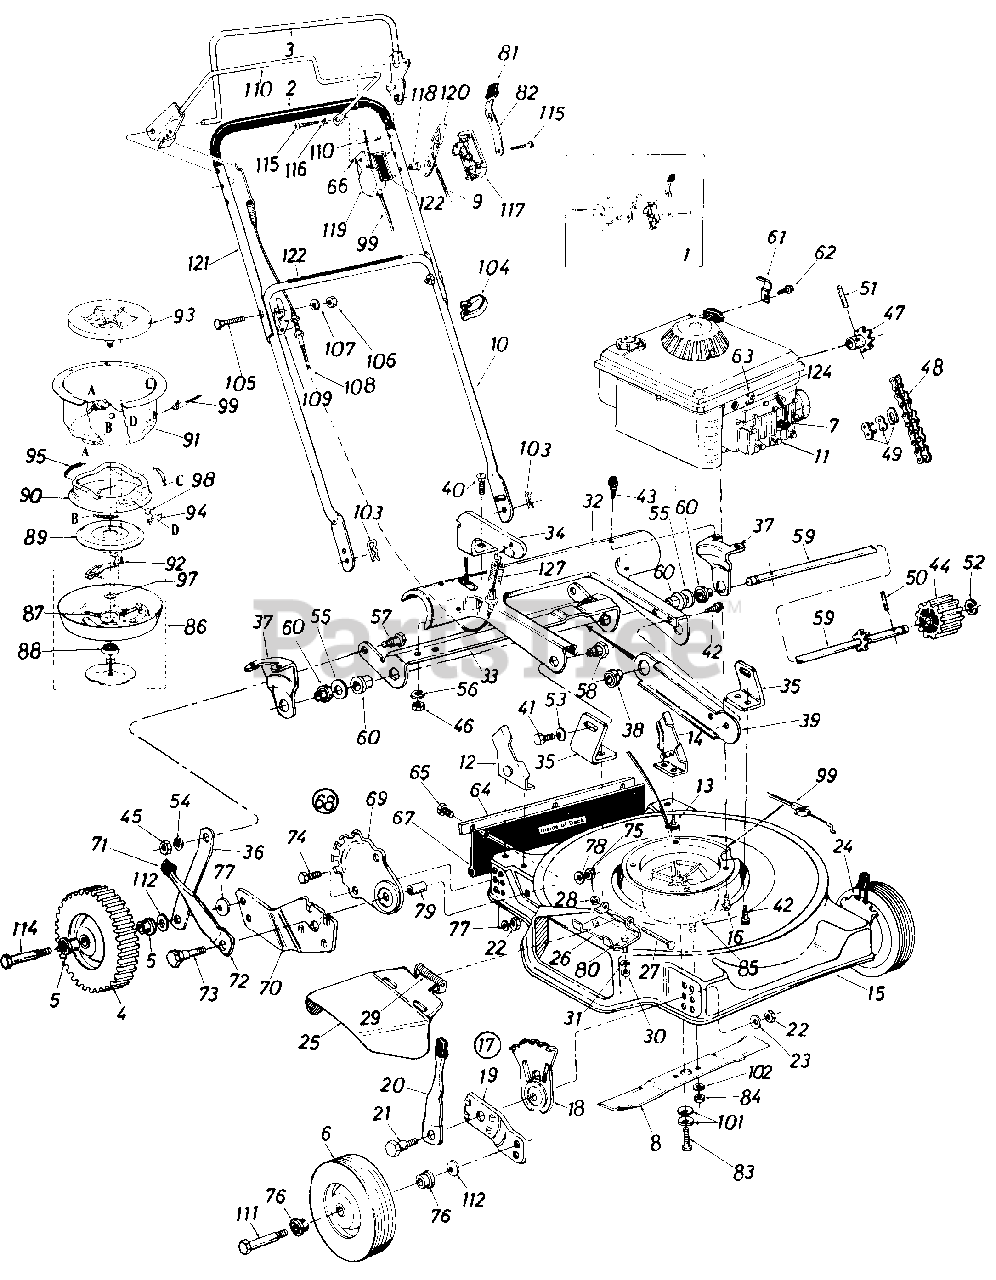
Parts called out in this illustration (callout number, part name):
1	Kit-Control Housing Comp.
3	Control Handle Ass'y. Comp.-L.H .
4	Rear Wheel Ass'y.-Comp. 8 x 1.75
5	Rear Wheel Brg.
7	Spark Plug Boot
8	22" Blade
9	Throttle Control Wire-53"
10	Lower Handle
11	Engine
12	Handle Brkt. Ass'y.-R.H.
13	Hex Wash. Hd. "B"-Tap Scr. 5/16-18 x .50" Lg.
14	Handle Brkt. Ass'y.-L.H.
15	22" Deck Ass'y.
16	Hex Wash. Hd. TT-Tap Scr. 3/8-16 x 1.00" Lg.
17	Height Adj. Ass'y. Comp.- R. H .
18	Height Adj. Plate
19	Pivot Bar
20	Spring Lever w/Knob
21	Shld. Bolt .500" Dia. x .375
22	Hex Nut 3/8-16 Thd.*
23	Bell-Wash. .39" I.D. x 1.4"
24	Height Adj. Ass y. Comp.-L.H.
25	Chute Deflector Ass'y. Comp.
26	Deflector Hinge Plate Ass'y.
27	Pivot Pin
28	Push Cap 1/4" Rod
29	Torsion Spring
30	Hex Nut 1/4-20 Thd.
31	L-Wash. 1/4" I.D.
32	Pinion Pivot Cover 22"
33	Cam
34	Engagement Arm
35	Pivot Bracket
36	Link 4.58" x .88" Wide
37	Axle Brkt.
38	Flange Ball Brg. .500" I.D.
39	Brg. Support
40	Carriage Bolt 1/4-20 x .50" Lg.
41	Hex Bolt 3/8-16 x .50" Lg.
42	Hex "B"-Tap Scr. 1/4 x .38"
43	Hex Wash. Hd. AB-Tap Scr. 1/4" x.62" Lg.
44	13 Teeth-Drive Pinion
45	Hex Nut 5/16-18 Thd.
46	Hex Nut 1/4-20 Thd.
47	10 Tooth Sprocket Ass'y.
48	#48 Chain 1/2" Pitch 49 Links
49	Master Link
50	Spring Pin Spir. 3/16" Dia. x 1.25" Lg.
51	Spring Pin Spir. 3/16" Dia. x 1.00" Lg.
52	"E"-Ring For. 500" Dia. Shaft
53	Bell-Wash. .400" I.D. x .88"
54	L-Wash. 5/16" I.D.
55	Fl-Wash. .531" I.D. x .930"
56	L-Wash. 1/4" I.D.
57	Shoulder Bolt .437" I.D. x .1 62
58	Shoulder Nut .625" Dia. x .1 65
59	Pinion Shaft wl7 Tooth Sprocket
60	Flange Brg. .506" I.D.
61	Casing Clamp
62	Hex "B" Tap Scr. #10 x .38" Lg.
63	Casing Clamp
64	Retaining Strip
65	Hex AB-Tap Scr. 1/4 x .62" Lg.
66	Fl-Wash. .203 I.D. x .406 O.D.
67	Rear Flap Ass'y.
68	Rear Height Adj. Ass'y. Comp.-R.H.
69	Index Plate
70	Pivot Bar-R.H.
71	Spring Lever Knob
72	Spring Lever
73	Shoulder Bolt .500" Dia. x .433" Lg.
74	Hex Bolt 3/8-16 x .75" Lg.
75	Hex Cent. L-Nut 5/16-18 Thd.
76	Front Wheel Bearing
77	Bell-Wash. .400" I.D. x .88"
78	Bell-Wash. .345" I.D. x .88"
79	Spacer.383" I.D. x .503" O.D. x .562" Lg.
80	Hex Bolt 1/4-20 x .50" Lg.
81	Spring Lever Knob
82	Lockout Lever
83	Hex Bolt 3/8-24 x 2.00" Lg. (Grade 8)
84	Hex Nut 3/8-24 Thd. (Grade 8)
85	Blade Brake Clutch Comp.
86	Clutch Blade Housing Ass'y.
87	Compression Spring .35" O.D. x 2.00" Lg.
88	Ball Brg. .669" I.D. x 1.574n
89	Clutching Cone
90	Brake Cup Cone
91	Clutch Housing
92	Hex Tap L-Scr. 1/4-20 x .75"
93	Fan Adapter
94	Ball Block
95	Extension Spring .35" O.D. x 1.75" Lg.
97	Fl-Wash. .690" I.D. x 1.060" O.D.
98	Steel Ball.500" Dia.
99	Clutch Cable-42.0"
101	Bell-Wash. .400" I.D. x .88"
102	L-Wash. 3/8" I.D.*
103	Intern. Cot. Pin 5/16" Dia.
104	Cable Tie
105	Curved Carriage Bolt 5/16-18 x 1.38" Lg.
106	Hex Nut 5/16-18 Thd.*
107	L-Wash. 5/16" I.D.*
108	Clutch Cable w/Spring
109	Cable Mtg. Brkt.
110	Control Handle
111	Shld. Bolt .448 Dia. x 1.450
112	Fl-Wash. .531" I.D. x .98n
114	Shld. Bolt .498" Dia. x 1.64
115	Truss Mach. Scr. #12 x 1.50" Lg.
116	Spacer.23" I.D.
117	Control Panel Half
118	Control Disc Pin
119	Clutch Panel Half
120	Throttle Control Lever
121	Upper Handle (Chrome)
122	Control Labels
124	Hex Wash. Hd. AB-Tap Scr. #8 x .38" Lg.
127	Compression Spring .47n O.D. x 1.93" Lg.
